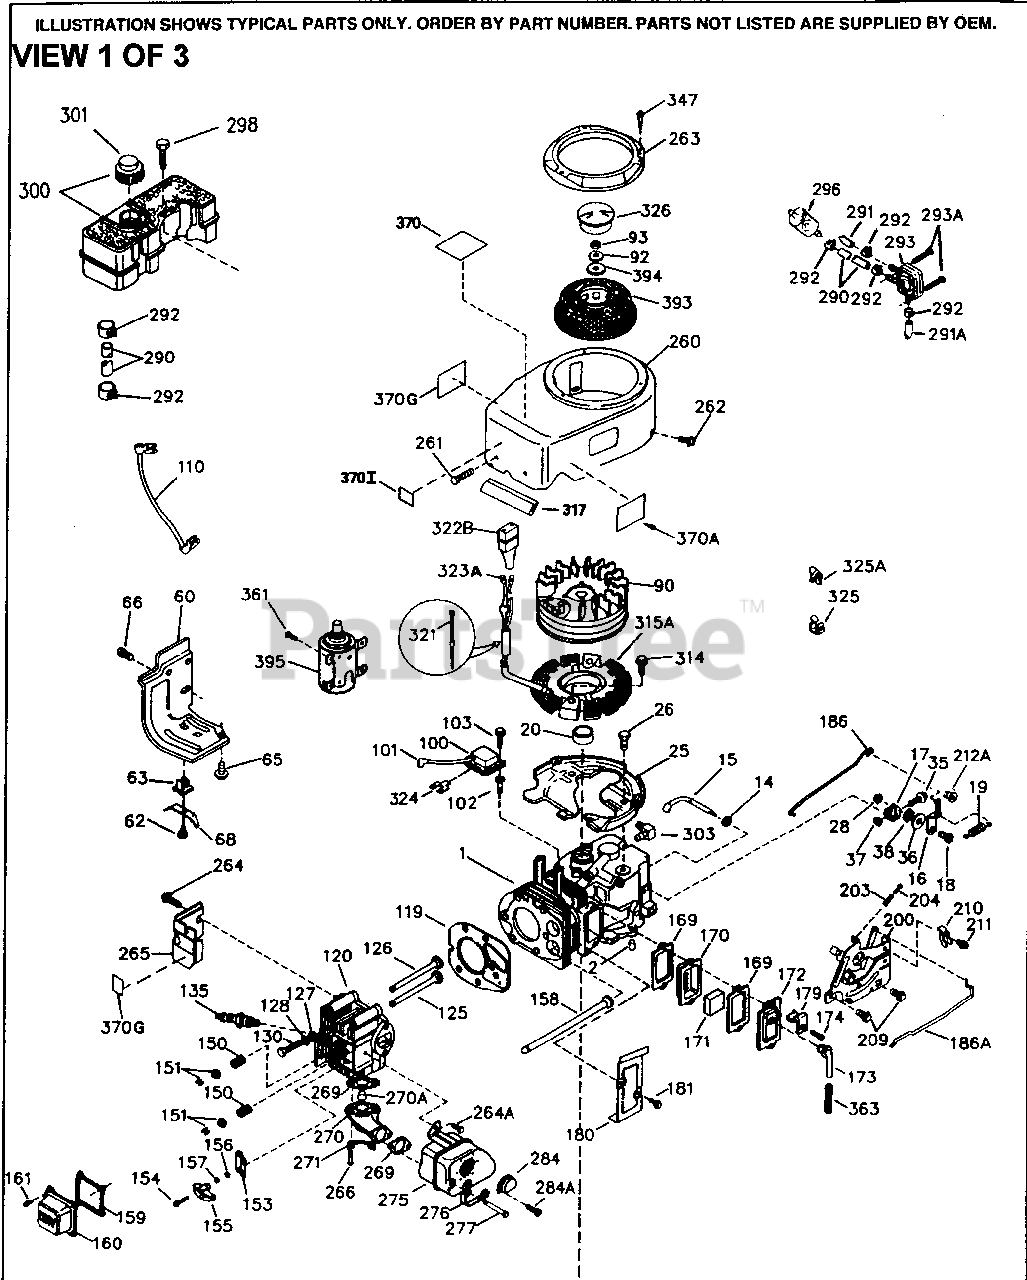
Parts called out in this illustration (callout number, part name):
1	"Cylinder (Incl. 2 & 20)
2	Dowel Pin
14	Flat Washer
15	Governor Rod
16	Governor Lever (Incl. 212A)
17	Governor Lever Clamp
18	Screw, Torx T-15, 8-32 x 3/8"
19	Extension Spring
20	Oil Seal
25	Blower Housing Baffle
26	Screw, 1/4-20 x 5/8"
28	Lock Nut, 8-32
35	Screw, 10-32 x 3/4"
36	Lock Washer #8
37	Lock Nut, 10-32
38	Retaining Ring
60	Blower Housing Extension
62	Screw, 8-32 x 3/8"
63	Breather Tube Grommet
65	Screw, 10-24 x 1/2"
66	Screw, T-30, 1/4-20 x 1/2"
68	Ground Terminal
90	Flywheel (W/Ring Gear)
92	Lock Washer
93	Flywheel Nut
100	Solid State Ignition
101	Spark Plug Cover
102	Solid State Mounting Stud
103	Screw, Torx T-15, 10-24 x 15/16"
110	Ground Wire
119	* Cylinder Head Gasket
120	Cylinder Head
125	Exhaust Valve (Std.)
125	Exhaust Valve (1/32" OS)
126	Intake Valve (Std.)
126	Intake Valve (1/32" OS)
128	Belleville Washer
130	Screw, 5/16-18 x 2-45/64"
135	Resistor Spark Plug (RN4C) also avail able in Packaged Part #740069
150	Valve Spring
151	Valve Spring Keeper
153	Push Rod Guide
154	Rocker Arm Stud
155	Rocker Arm
156	Lock Washer
157	Lock Nut, 5/16-24
158	Push Rod
159	* Rocker Arm Cover Gasket
160	Rocker Arm Housing
161	Screw, T-30, 1/4-20 x 1/2"
169	* Valve Cover Gasket
170	Breather Body
171	Breather Element
172	Valve Cover
173	Breather Tube
174	Screw, 10-24 x 1/2"
180	Blower Housing Extension
181	Screw, 10-24 x 9/16"
186	Governor Link
186A	Choke Link
200	Control Bracket (Incl. 203 & 204)
203	Compression Spring
204	Screw, 6-32 x 21/32"
209	Screw, 10-32 x 7/16"
210	Conduit Clip
211	Screw, 10-32 x 3/8"
212A	Bushing
260	Blower Housing
261	Screw, 1/4-20 x 9/16"
262	Screw, T-40, 5/16-24 x 21/32"
263	Trim Ring
264	Screw, 5/16-18 x 5/8"
264A	Screw, T-30, 1/4-20 x 1/2"
265	Cylinder Head Cover
270A	Exhaust Port Liner
290	Fuel Line (8.62")
292	Fuel Line Clamp
296	Fuel Filter (Incl. 292) also availabl e as Packaged Part #740003B
314	Screw, 1/4-20 x 3/4"
322B	Connector Body
323A	Terminal
323B	Terminal
324	Terminal
325	Wire Clip
326	Blower Housing Plug
347	Screw, 10-32 x 9/16"
900	Replacement Engine 752328, order from 71-999
900	Replacement Short Block 752321, order from 71-999
